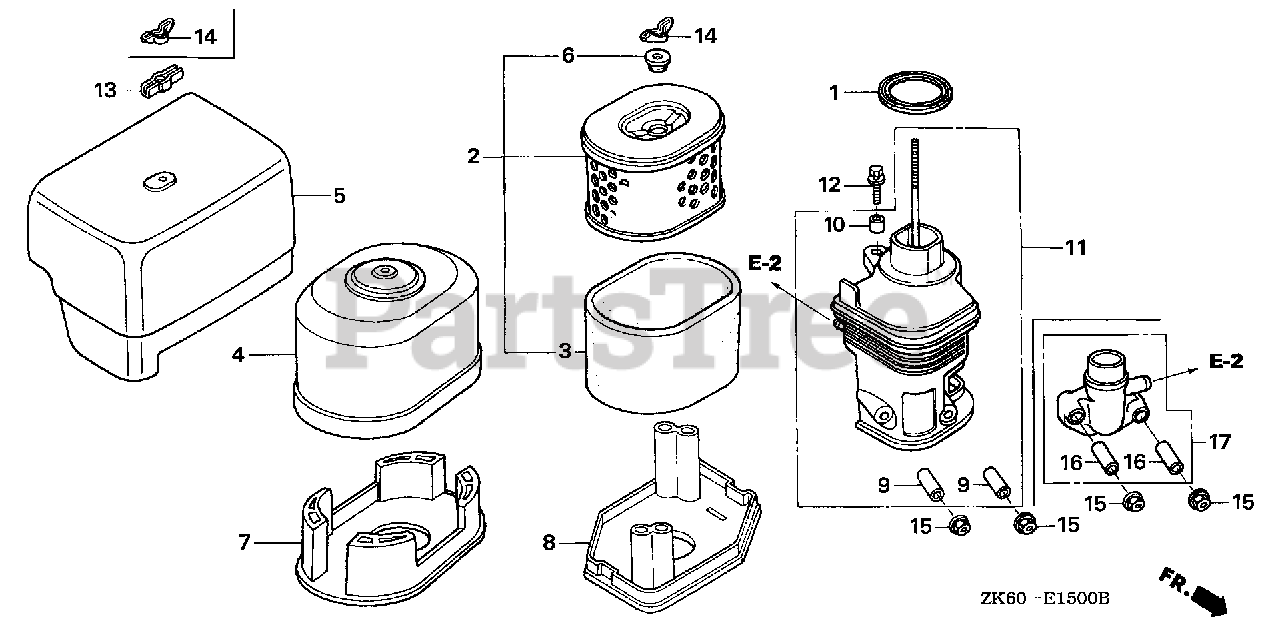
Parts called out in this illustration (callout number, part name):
1	GASKET, ELBOW
2	ELEMENT, AIR CLEANER
3	FILTER (OUTER)
5	COVER, AIR CLEANER
6	GROMMET, AIR CLEANER
8	NOSE, MUFFLER
9	COLLAR, AIR CLEANER
10	COLLAR B, AIR CLEANER
11	ELBOW, AIR CLEANER
12	BOLT-WASHER (6X22)
13	WINGNUT (6MM) (BLACK)
14	NUT, TOOL BOX SETTING
15	NUT, FLANGE (6MM)
